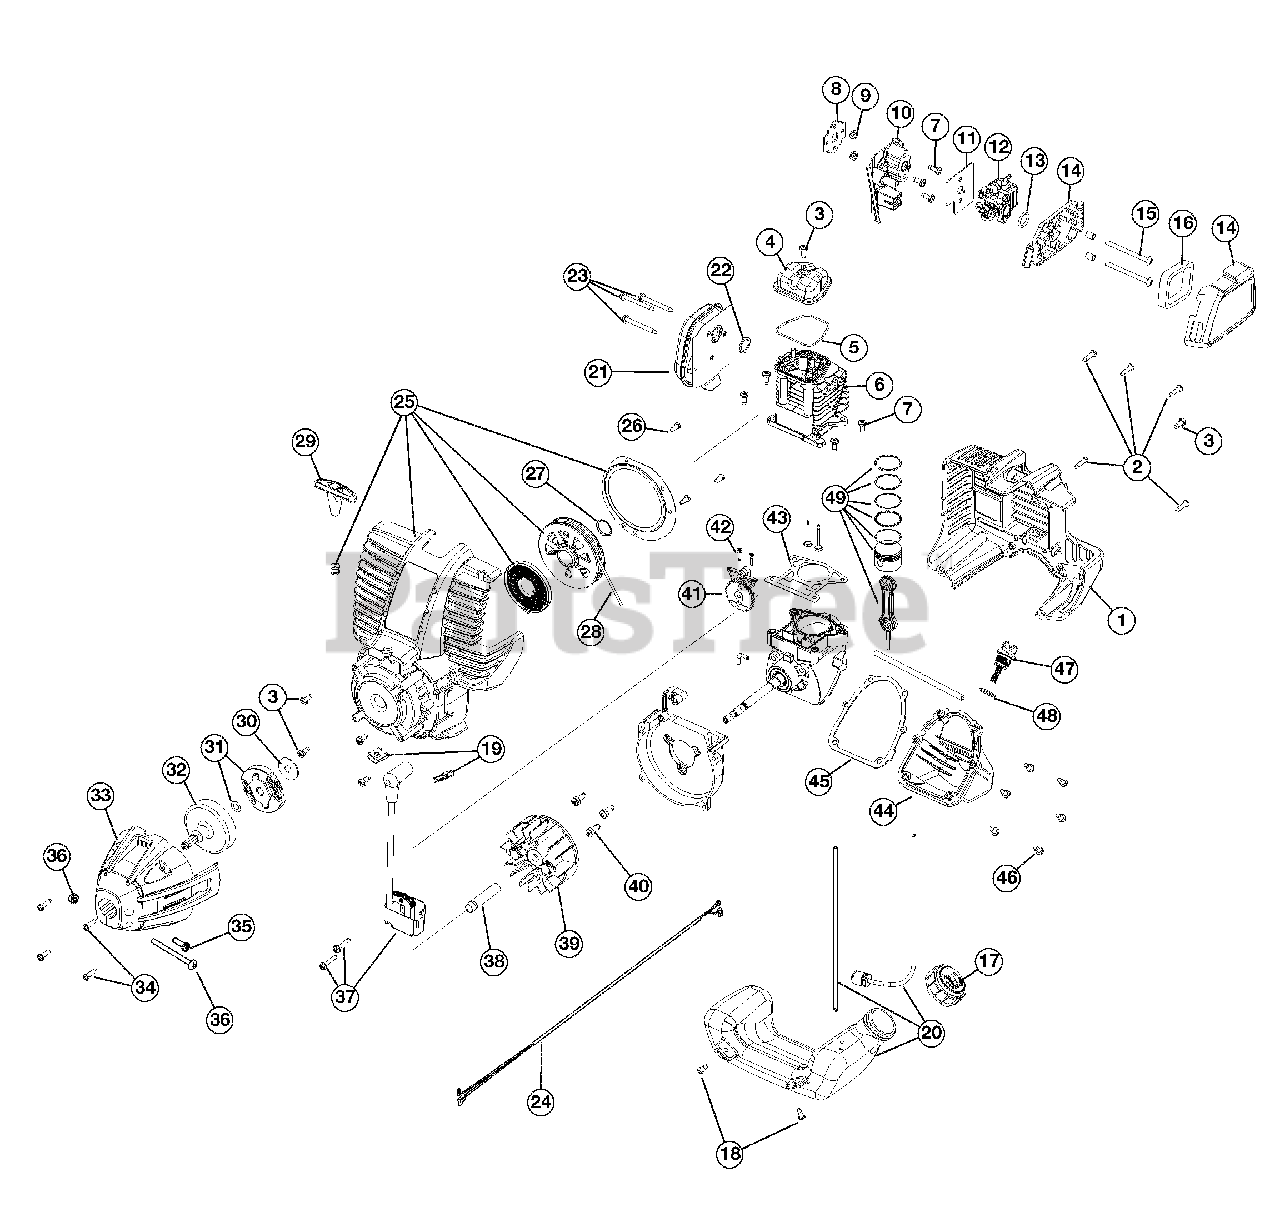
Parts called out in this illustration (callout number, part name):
1	Engine Cover
4	Valve Cover
5	Valve Cover Gasket
6	Cylinder Assembly
7	Cylinder Screw
8	Insulator Gasket
11	Carburetor Gasket
12	Carburetor with Primer
13	Carburetor O-Ring
14	Air Filter Cover Assembly
15	Air Filter Mounting Screw
16	Air Filter
20	Fuel Tank Assembly
21	Muffler Assembly
22	Muffer Gasket
23	Muffler Mounting Screw
25	Starter Housing Assembly
26	Plate Screw
29	Pull Handle
31	Clutch Assembly
32	Clutch Drum
33	Clutch Cover Assembly
34	Cover Screw
35	Anti-Rotation Screw
36	Clamping Screw Assembly
37	Ignition Module Assembly
40	Shroud Screw
41	Cam Bracket Assembly
42	Cam Bracket Screw
43	Cylinder Gasket
45	Oil Pan Gasket
46	Oil Pan Screw
47	Dipstick Assembly
49	Piston Assembly
